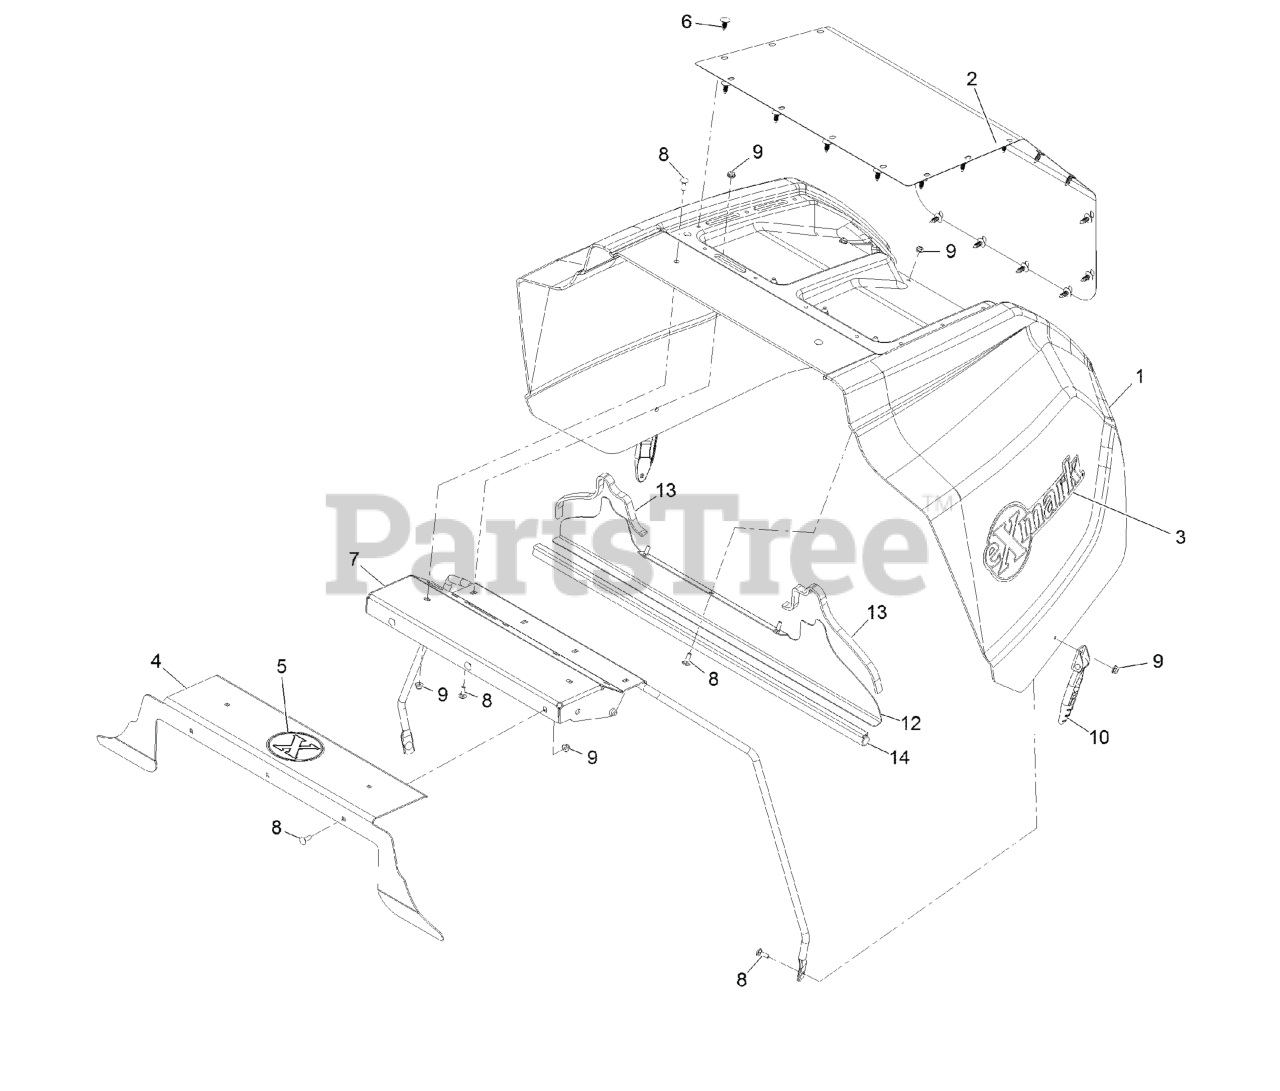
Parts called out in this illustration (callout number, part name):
1	HOOD
2	Screen-Intake
3	DECAL-EXMARK
4	HOOD-BLOCK OFF
5	DECAL-X-LOGO
6	PLUG-PLASTIC
7	SUPPORT-HOOD
8	BOLT-CARR
10	LATCH-RUBBER
12	PLATE-SEAL
13	SEAL-FOAM
14	Seal-Bulb
